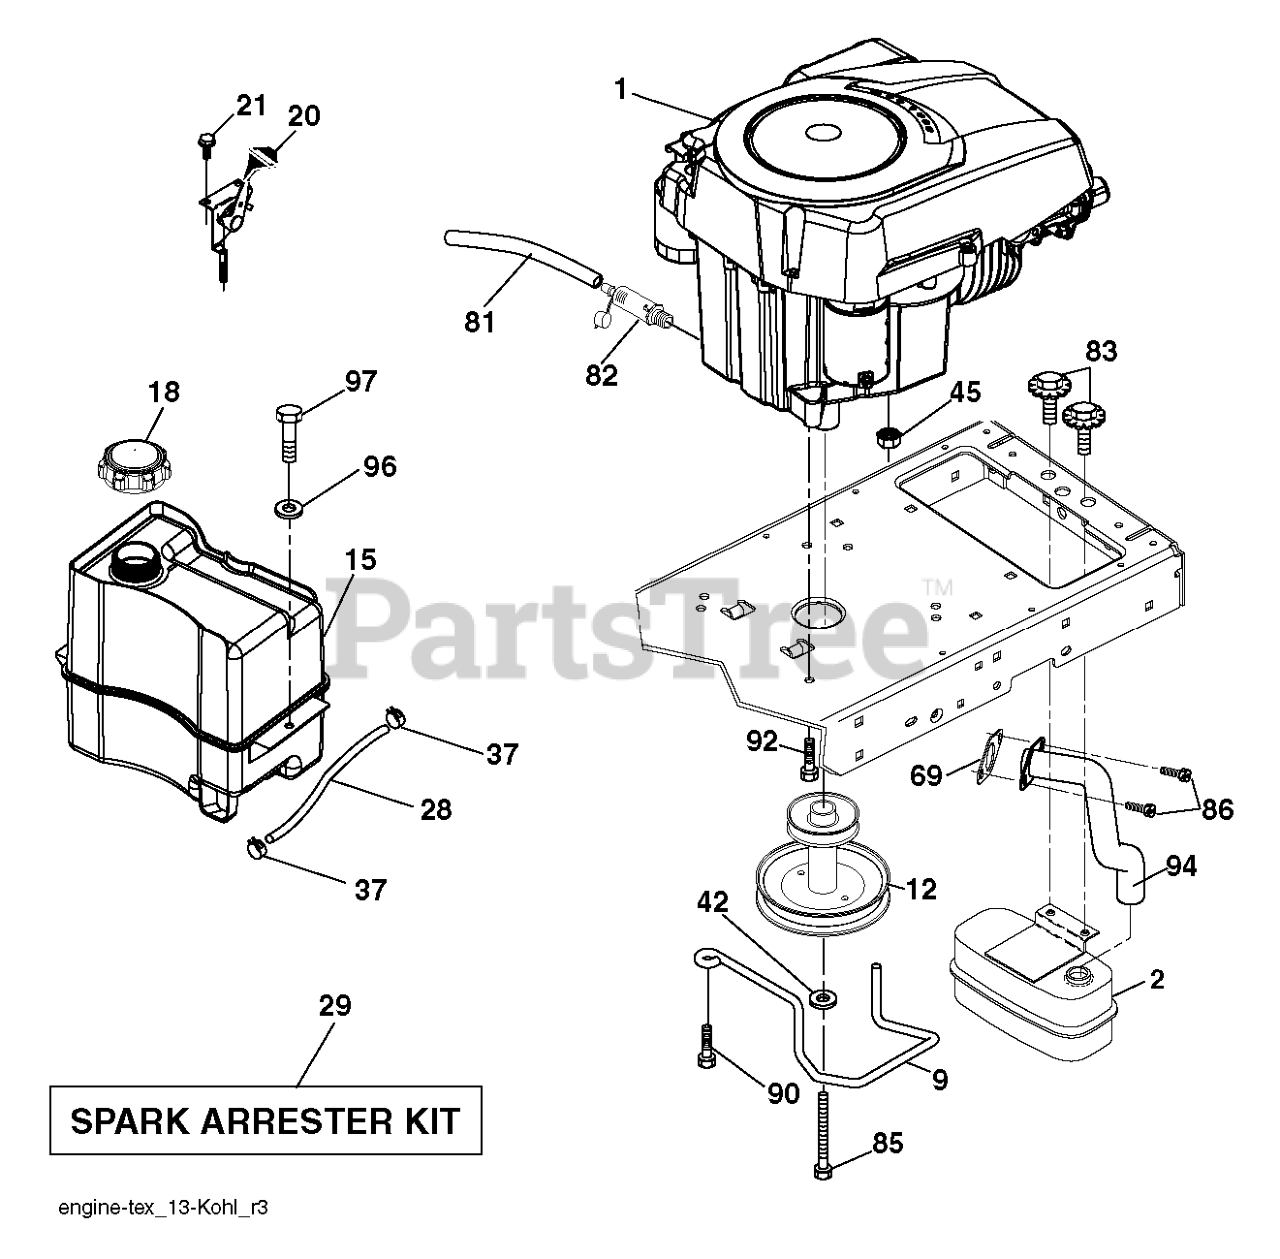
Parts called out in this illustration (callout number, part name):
2	MUFFLER.SINGLE.LRG.BRIGGS.KOHL
9	KEEPER.BELT.ENGINE.3.25 (3 2)
12	PULLEY ENGINE
15	RP TANK FUEL FRT 1.5 GAL
18	FUEL CAP
20	CONTROL.TH/CK.C.
21	SCREW
28	LINE.FUEL.20
29	KIT.SPARK ARRESTOR 794945 B&S
37	HOSE CLAMP
41	LOCKWASHER
43	BOLT HEX 7/16-20X4-1/4"
45	NUT
69	GASKET.EXHAUST.KOHLER
79	SCREW.SOCKET HD.5/16-1
81	TUBE, DRAIN OIL ASM.
82	PLUG DRAIN OIL EASY
83	BOLT.5/16-18UNCX3/4 W/SEMS.BLK
90	SCREW 3/8-16X1
92	SCREW 3/8-16X1
94	RP.TUBE.EXHAUST.KOHL.COURAGE
97	SCREW HEXWSHR 1/4-20X3/4
